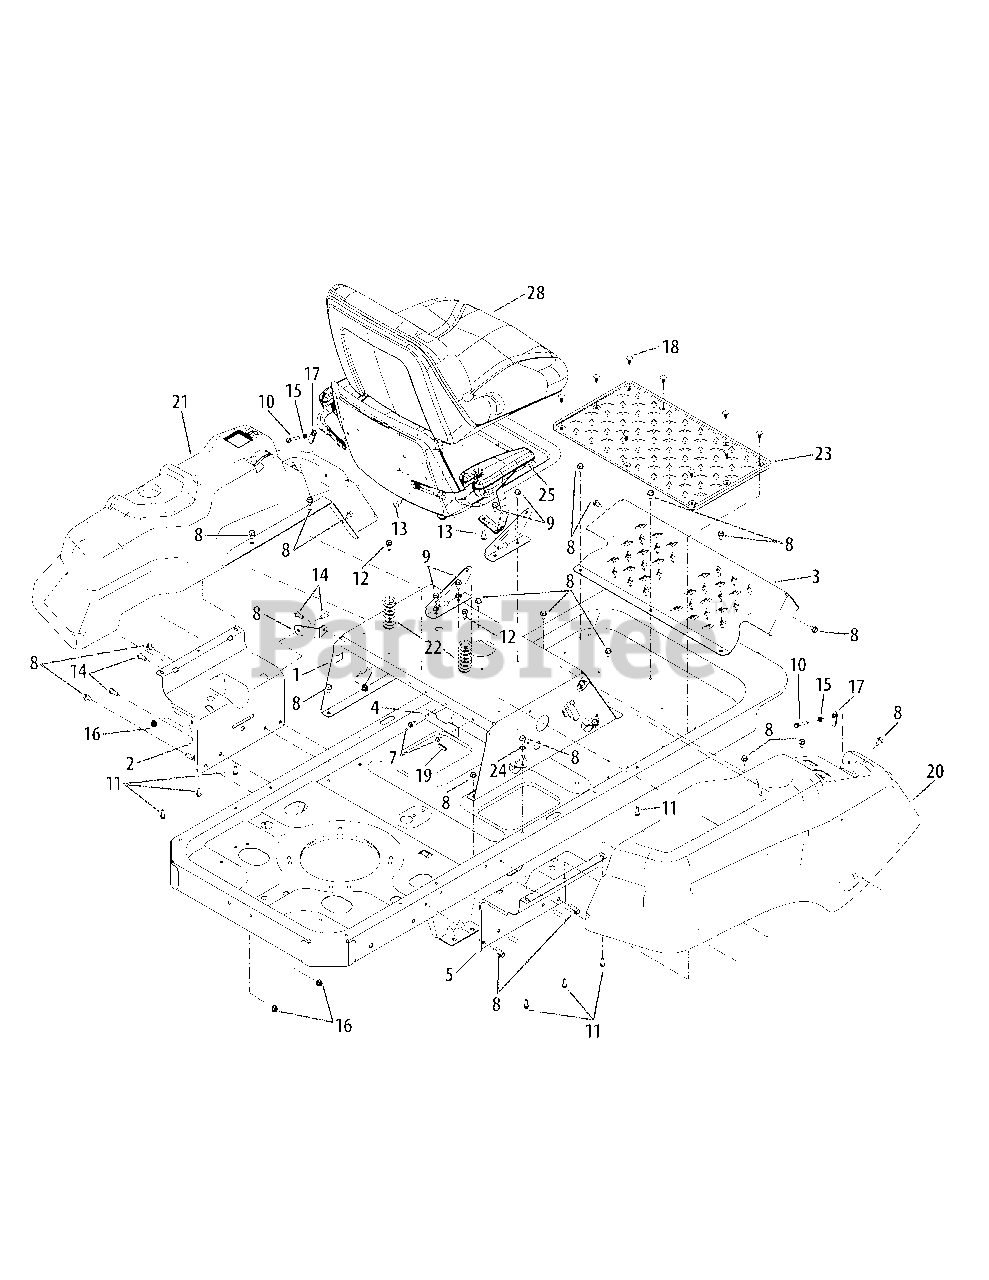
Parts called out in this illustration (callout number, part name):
7	Hex Washer Hd. Screw, 1/4-20 x .500
8	Hex Washer Hd. Screw, 5/16-18 x .625
9	Hex Washer Hd. Screw, 5/16-12 x .750
10	Hex Wshr. Hd. Screw, 1/4-20 x 1.500
11	Hex Wshr. Hd. Screw, 1/4-15 x .750
12	Hex Washer Hd. Screw, 5/16-18 x .750
13	Screw, 5/16-18 x .750
14	Hex Screw, 5/16-18 x .75
15	Jam Nut, 1/4-20
16	Flangelock Nut, 5/16-18
17	Speed Nut, 1/4-20
18	Ratchet Clip, .250
19	Trim Strip
20	Console (RH)
21	Console (LH)
22	Compression Spring, 1.28 x 3.125
23	Foot Pad
24	External Tooth Lock Washer, 3/8
25	High Back Seat Arms
